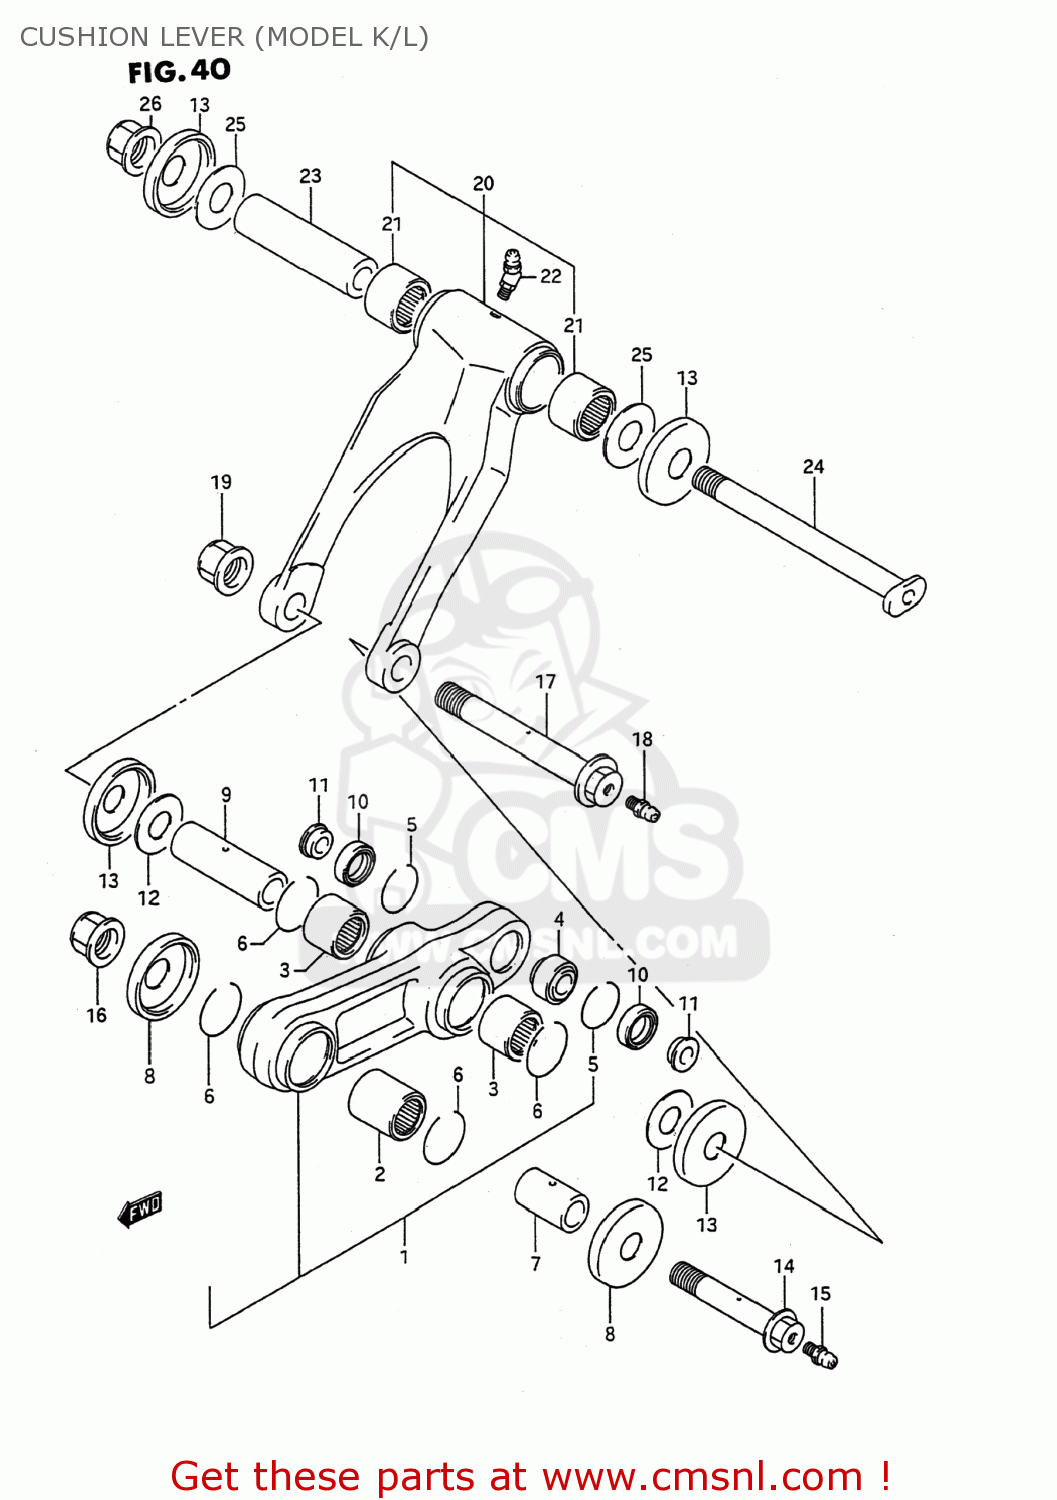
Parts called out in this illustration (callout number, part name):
1	LEVER SET,REAR CUSHION
2	BEARING(20X27X25)
3	BEARING(20X27X20)
4	BEARING,RR CUSHION LEVER
5	RING
6	CIRCLIP
7	SPACER,RR CUSHION LEVER FR
8	SEAL,REAR CUSHION LEVER
9	SPACER,RR CUSHION LEVER CTR
10	SEAL,OIL(17X24X3)
11	COLLAR
12	WASHER
13	SEAL,RR CUSHION LEVER
14	BOLT,REAR CUSHION LEVER
15	GREASE NIPPLE
16	NUT 12MM
17	BOLT,REAR CUSHION LEVER
18	GREASE NIPPLE
19	NUT
20	ROD SET,REAR CUSHION,LEFT
21	BEARING(20X27X20)
22	NIPPLE,GREASE
23	SPACER,RR CUSHION ROD
24	BOLT,REAR CUSHION ROD
25	WASHER
26	NUT
